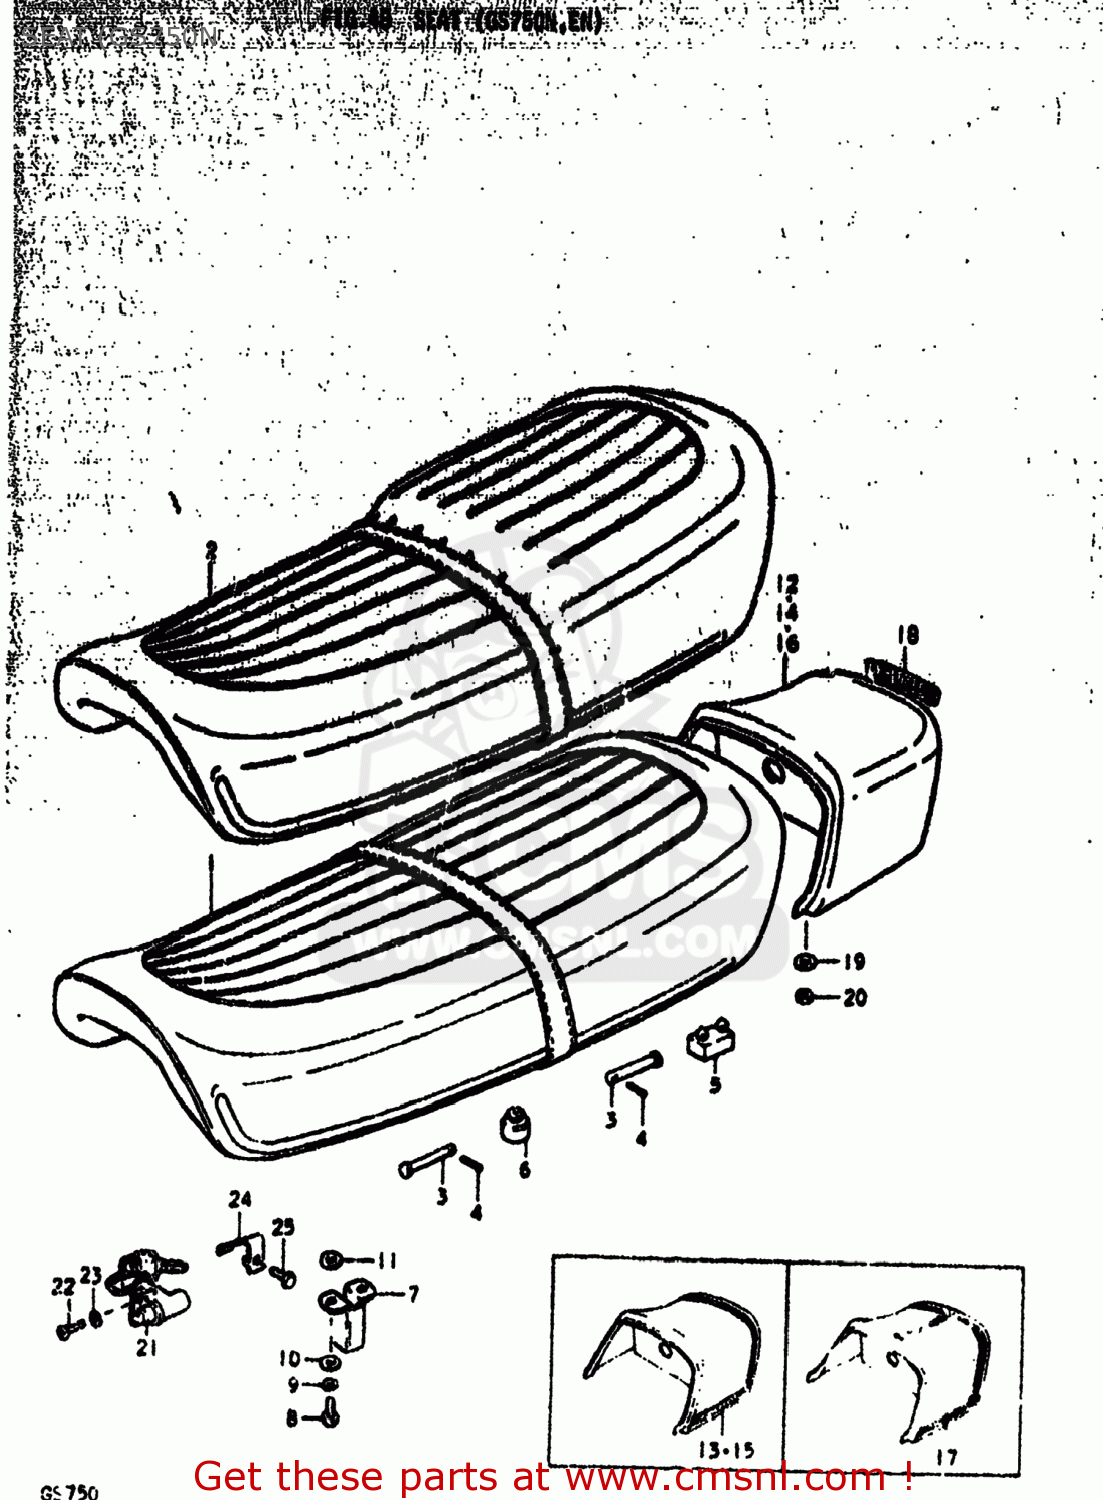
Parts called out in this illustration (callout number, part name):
1	SEAT ASSEMBLY
2	SEAT ASSEMBLY
3	PIN
4	PIN
5	CUSHION
6	CUSHION
7	STRIKER,SEAT LOCK
8	BOLT
9	LOCK WASHER
10	WASHER
11	WASHER(8.5X18X1)
12	COVER,SEAT TAIL
14	COVER,SEAT TAIL
16	COVER,SEAT TAIL
17	TAPE SET
18	EMBLEM,SEAT TAIL COVER
19	WASHER
20	NUT 16MM
21	LOCK ASSY,SEAT
22	SCREW
23	LOCK WASHER
24	SPRING,HELMET HOLDER
25	BOLT 5X16
